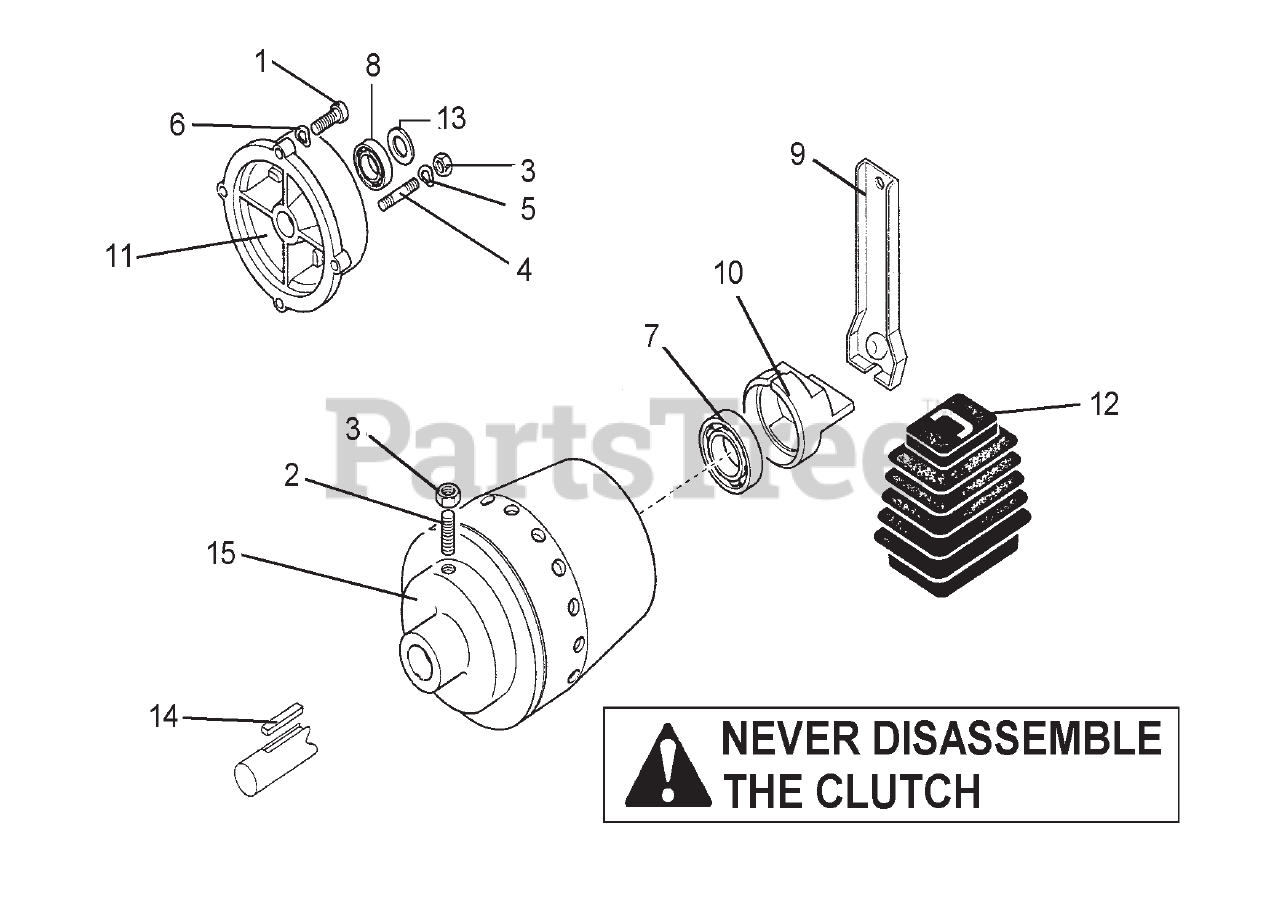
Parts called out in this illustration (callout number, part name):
1	SCREW, 3/8X1"
2	SCREW, M8X35
3	NUT, M8
4	STUD, M8X40X14X14
5	WASHER, WAVEY
6	WASHER, WAVEY
7	BEARING, M17X40X12
8	BEARING, M20X47X14
9	LEVER, RECOIL START
10	CONE PUSHER
11	FLANGE
13	WASHER
15	CLUTCH, 6.5HP (INCLUDE 6 & 9)
